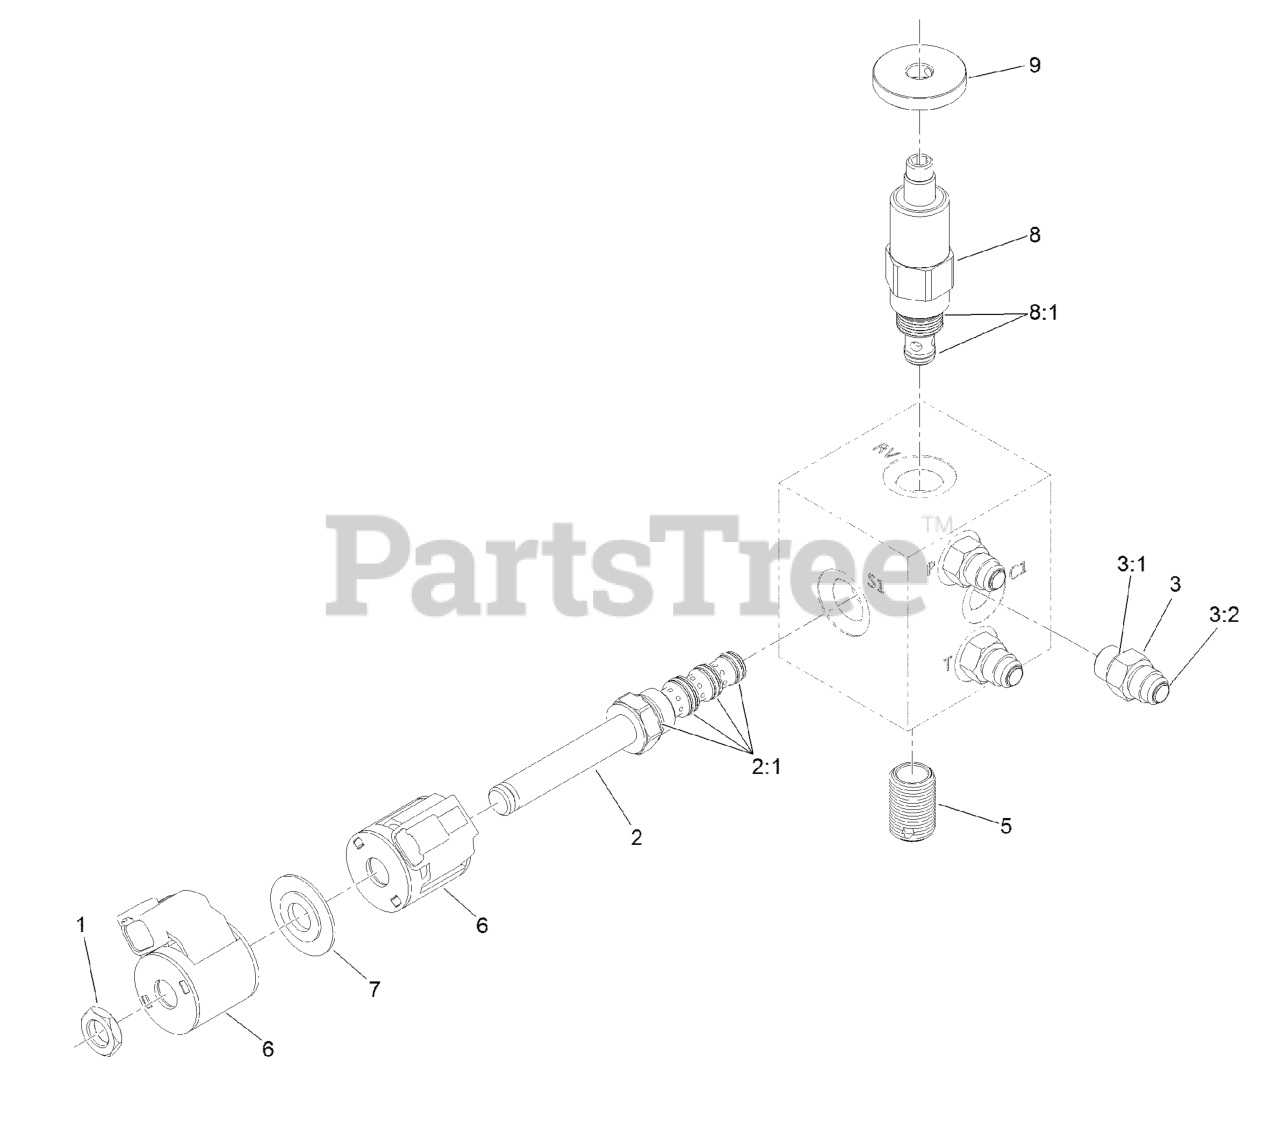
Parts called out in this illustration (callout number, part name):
1	NUT-COIL
2	VALVE-SOLENOID
2:1	Seal Kit
3	FITTING-STRAIGHT
3:1	BOSS O-RING
5	Nipple-Filter
6	E Coil-12V Dc
7	Spacer-Coil
8	VALVE-RELIEF, POPPET TYPE
8:1	SEAL KIT
9	KNOB (1.5 DIA)
